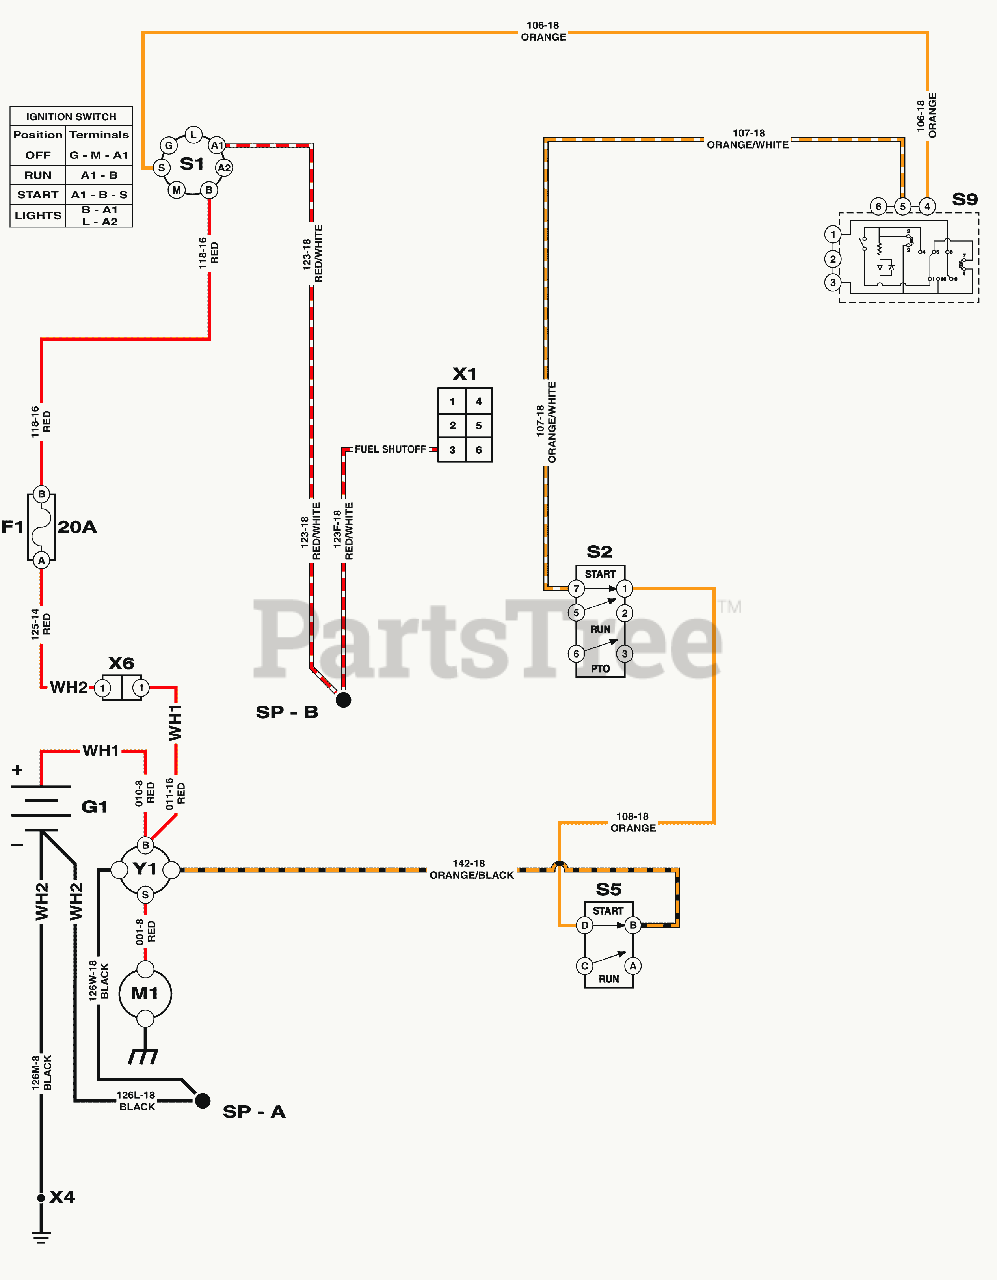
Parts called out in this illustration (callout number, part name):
F1	FUSE, Wiring Harness
G1	BATTERY, 12 Volt, 230 CCA
M1	MOTOR, Starter
S1	SWITCH, Ignition
S2	SWITCH, PTO Push/Pull, Yel Knob w/Symbols, 8 Terminal
S5	SWITCH, DP, NO/NC, Snap-In
S9	SWITCH, Reverse Mow Option
WH1	HARNESS, Battery, Solenoid
WH2	HARNESS, Main
X1	CONNECTOR, Engine
X4	CHASSIS GROUND POINT
X6	CONNECTOR, Battery Solenoid Harness to Main Harness
Y1	SOLENOID
